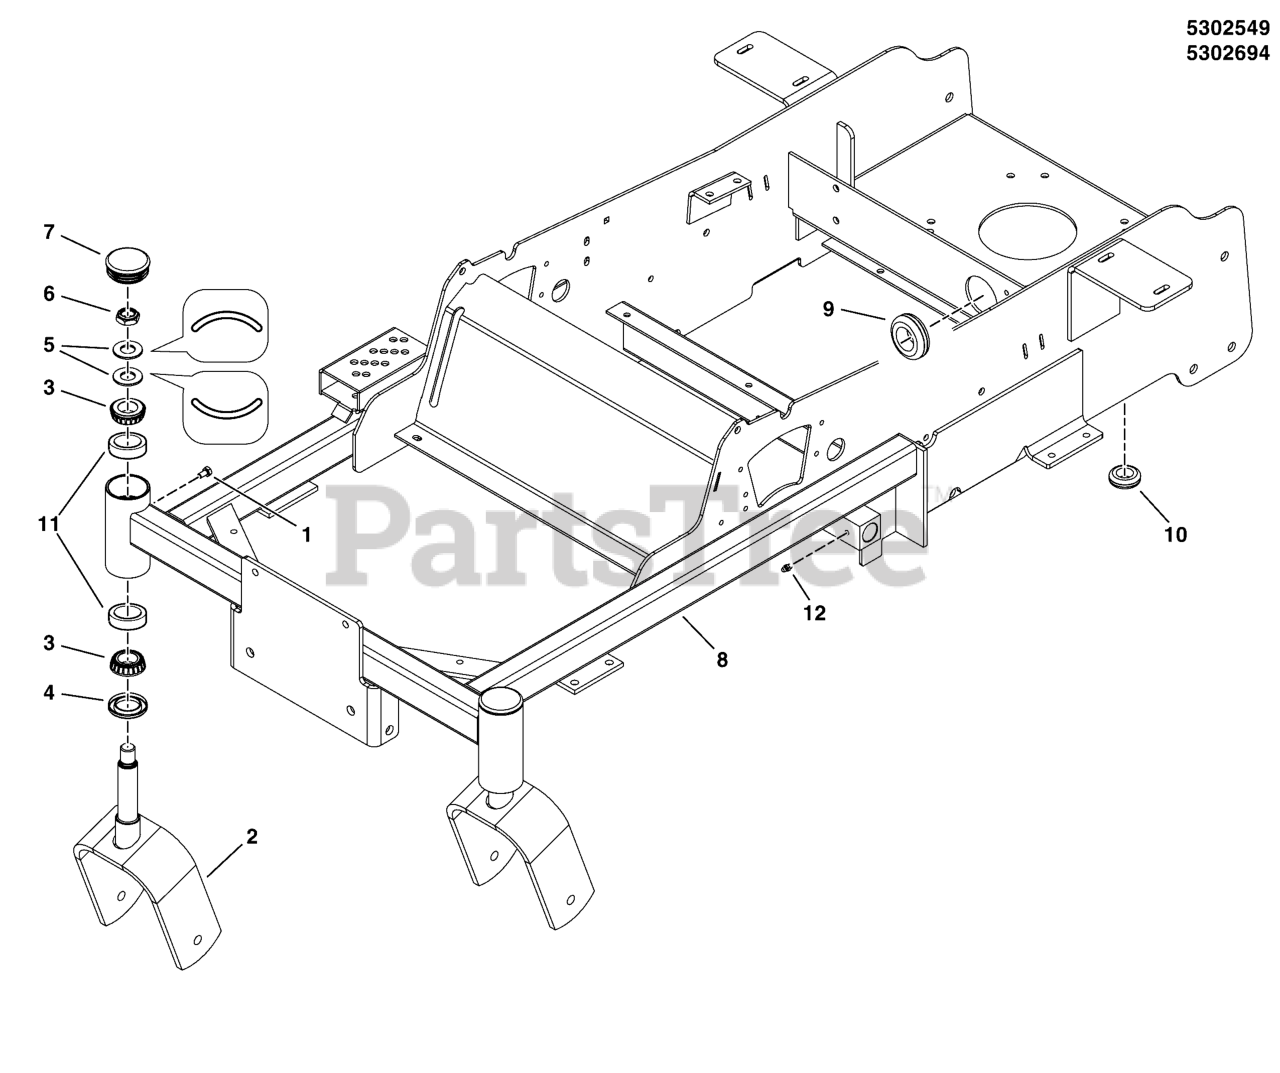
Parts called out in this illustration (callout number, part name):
1	BOLT, 1/4-28 X 1/2, GD5 YZ
2	WELD, CASTER YOKE - RED
3	BEARING, TAPERED ROLLER, 1"
4	SEAL, GREASE
5	WASHER, BELLEVILLE - 1.500 X .755
6	NUT, 3/4-16, HEX JAM NYLON LOCK
7	CAP, GREASE, LOW PROFILE
8	* WELD, FRAME, S50XT - RED
9	GROMMET, 2" ID
10	GROMMET, 7/8
11	CUP, BEARING
12	GREASE FITTING, 1/4-28 STRAIGHT
